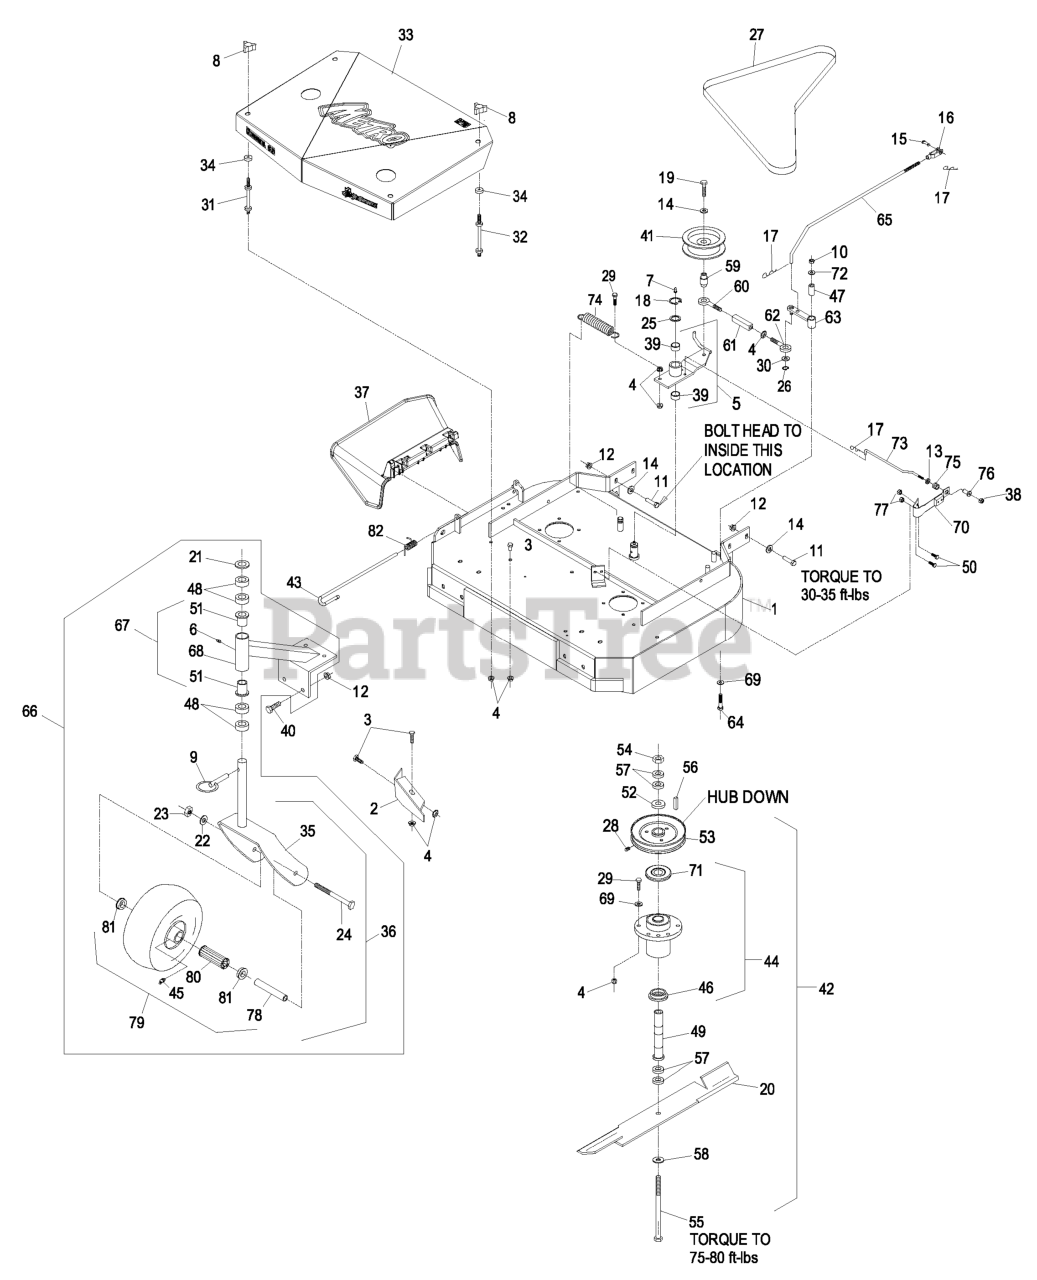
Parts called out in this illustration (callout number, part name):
1	ASM,DECK 36 RIGID
2	BAFFLE-DOGLEG
3	SCREW-HH
5	IDLER ARM ASM
6	FITTING-GREASE
7	FITTING-GREASE
8	KNOB-3 PRONG
10	NUT-LOCK, NI
11	SCREW-HH
12	NUT-HHF, WHIZ
13	RING-PUSH ON
14	WASHER-BELLEVILLE
15	PIN-CLEVIS
16	YOKE-ADJUSTABLE
17	PIN-COTTER
18	RING-RETAINING, EXT
19	SCREW-HH
21	WASHER-FLAT
22	WASHER-LOCK
23	NUT-HH
24	SCREW-HH
25	WASHER-SPINDLE
26	RING-RETAINING, EXT
27	BELT,BLADE METRO 36
28	SCREW-SET
29	SCREW-HH
30	WASHER-PLAIN
31	STUD-SHIELD, BELT (SHORT)
32	STUD-SHIELD, BELT (LONG)
33	ASM,SHIELD W/DECALS 36 ME
36	ASM,CASTER/WHEEL
37	CHUTE DEFLECTOR XRK M056
38	NUT-LOCK, NI
39	SLEEVE-BEARING
40	SCREW-HH
42	ASM, CUTTER HOUSING OUTER
43	PIN-CHUTE
44	KIT, CUTTER HOUSING
45	FITTING-GREASE
46	SPACER-GUARD, BOTTOM
47	TUBE-PIVOT
48	SPACER-CASTER
49	TUBE-SPINDLE, SHORT
50	SCREW-HH
51	BEARING-FLANGED
52	WASHER-RETAINER, SHEAVE
53	SHEAVE
54	NUT-HEX
55	SCREW-CAP, HH
58	WASHER-SPRING
59	BUSHING-ENGAGEMENT
60	EYEBOLT-THREAD, LH
61	BODY-TURNBUCKLE
62	EYEBOLT-THREAD, RH
63	ARM-ASSIST, 32/36
64	SCREW-HH
65	ARM-ASSIST, LINKAGE
66	ASM,CASTER/MOUNT
67	SUPPORT ASM
69	WASHER-SPRING
70	PAD AND SPRING ASM
71	GUARD-BEARING, TOP
72	WASHER-FLAT
73	ROD-BRAKE
74	SPRING-EXTENSION
75	SPRING-COMPRESSION
76	SPACER-FLANGED
77	NUT-LOCK, NI
79	KIT, SP CASTER WHEEL REPL
80	BEARING
81	BUSHING
82	SPRING, TORSION
